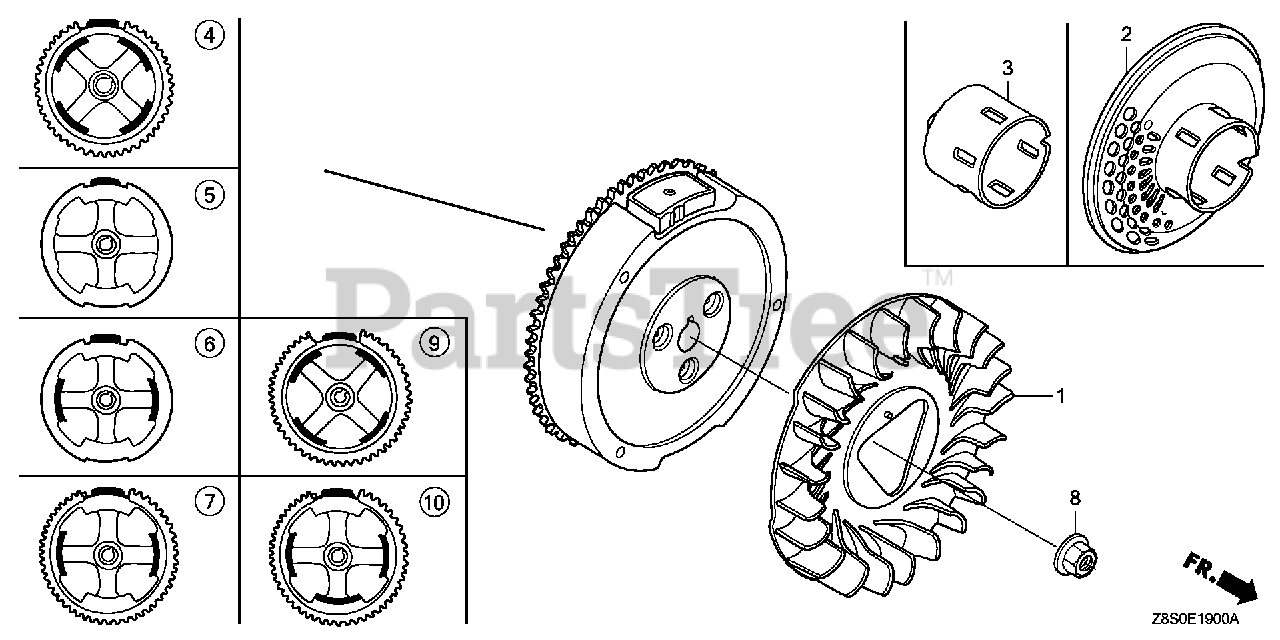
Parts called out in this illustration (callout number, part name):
1	FAN, COOLING
2	PULLEY, STARTER (SCREEN GRID)
8	NUT, SPECIAL (16MM)
